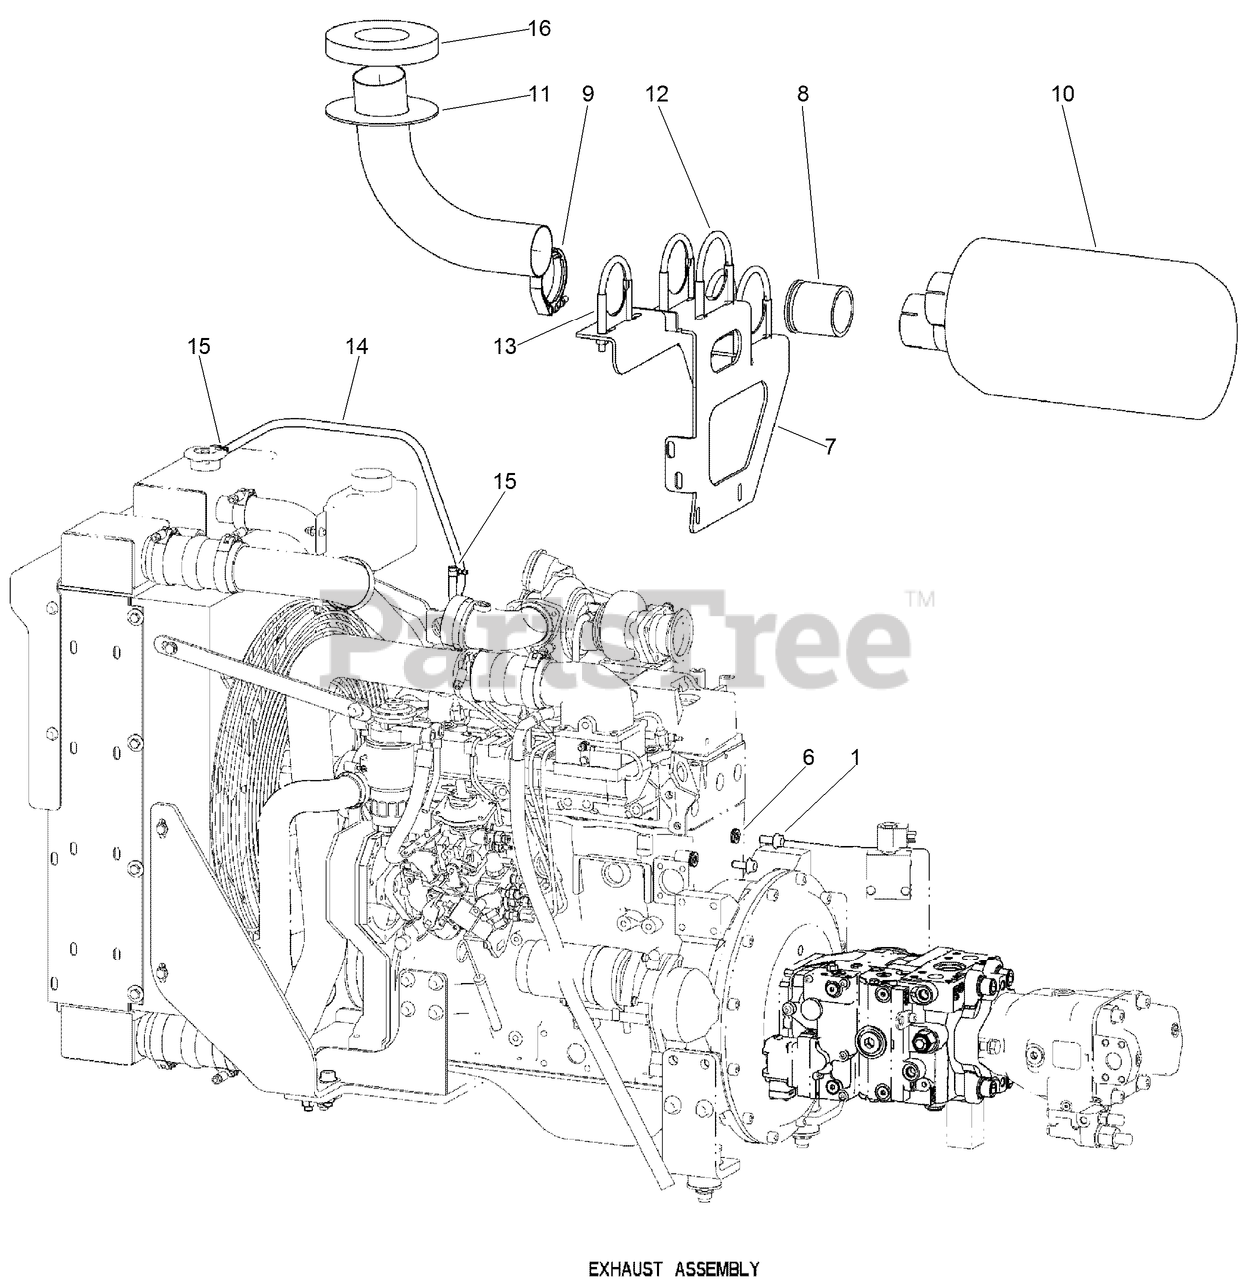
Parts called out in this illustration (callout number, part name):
1	SCREW-FLANGE
6	WASHER-FLAT
7	ASSEMBLY - Muffler Mount
8	FLANGE-ADAPTER, TURBO
9	CLAMP - T-Bolt
10	ASSEMBLY - Muffler
11	TUBE-EXHAUST (W/ SEAL PLATE)
12	CLAMP-GUILLOTINE
13	CLAMP-GUILLOTINE
14	OVERFLOW LINE - 3/8 ID x 32 Length
15	CLAMP - Hose Type M # 06
16	INSULATION
